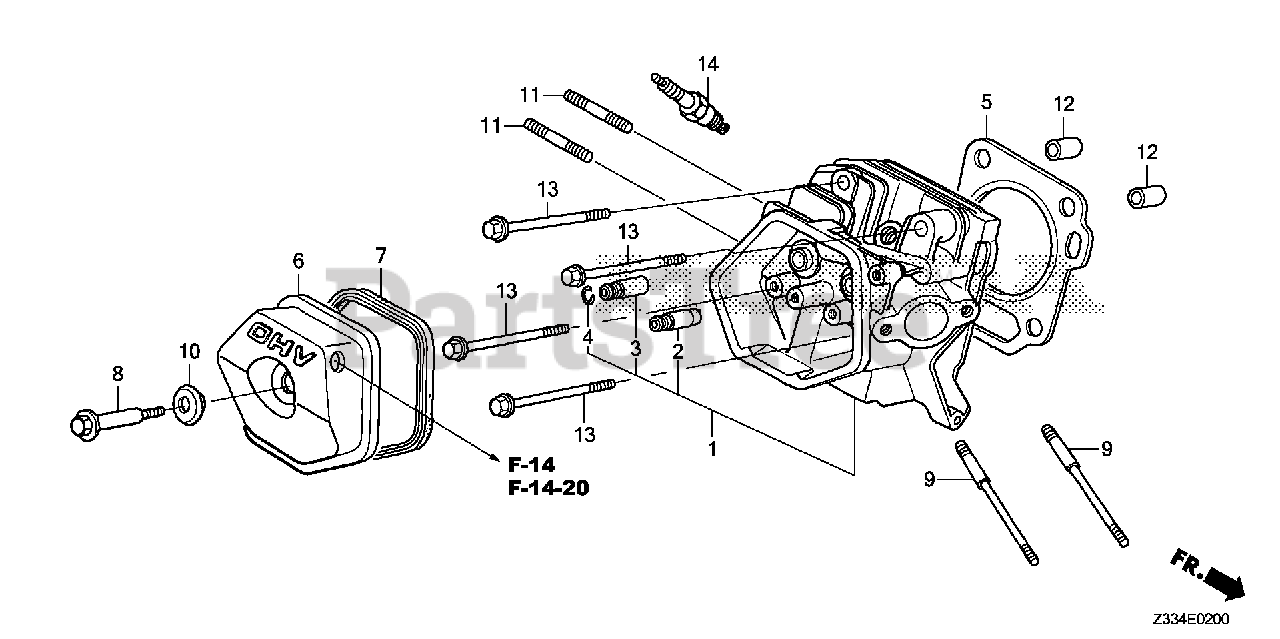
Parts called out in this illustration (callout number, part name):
1	CYLINDER HEAD
2	GUIDE, VALVE (OVER SIZE)
3	GUIDE, EX. VALVE (OVER SIZE)
4	CLIP, VALVE GUIDE
5	GASKET, CYLINDER HEAD
6	COVER, HEAD
7	GASKET, HEAD COVER
8	BOLT, HEAD COVER
9	BOLT, STUD (8X106)
10	WASHER, HEAD COVER
11	BOLT, STUD (8X32)
12	PIN, DOWEL (12X20)
13	BOLT, FLANGE (10X80)
14	SPARK PLUG (BPR5ES) (NGK)
